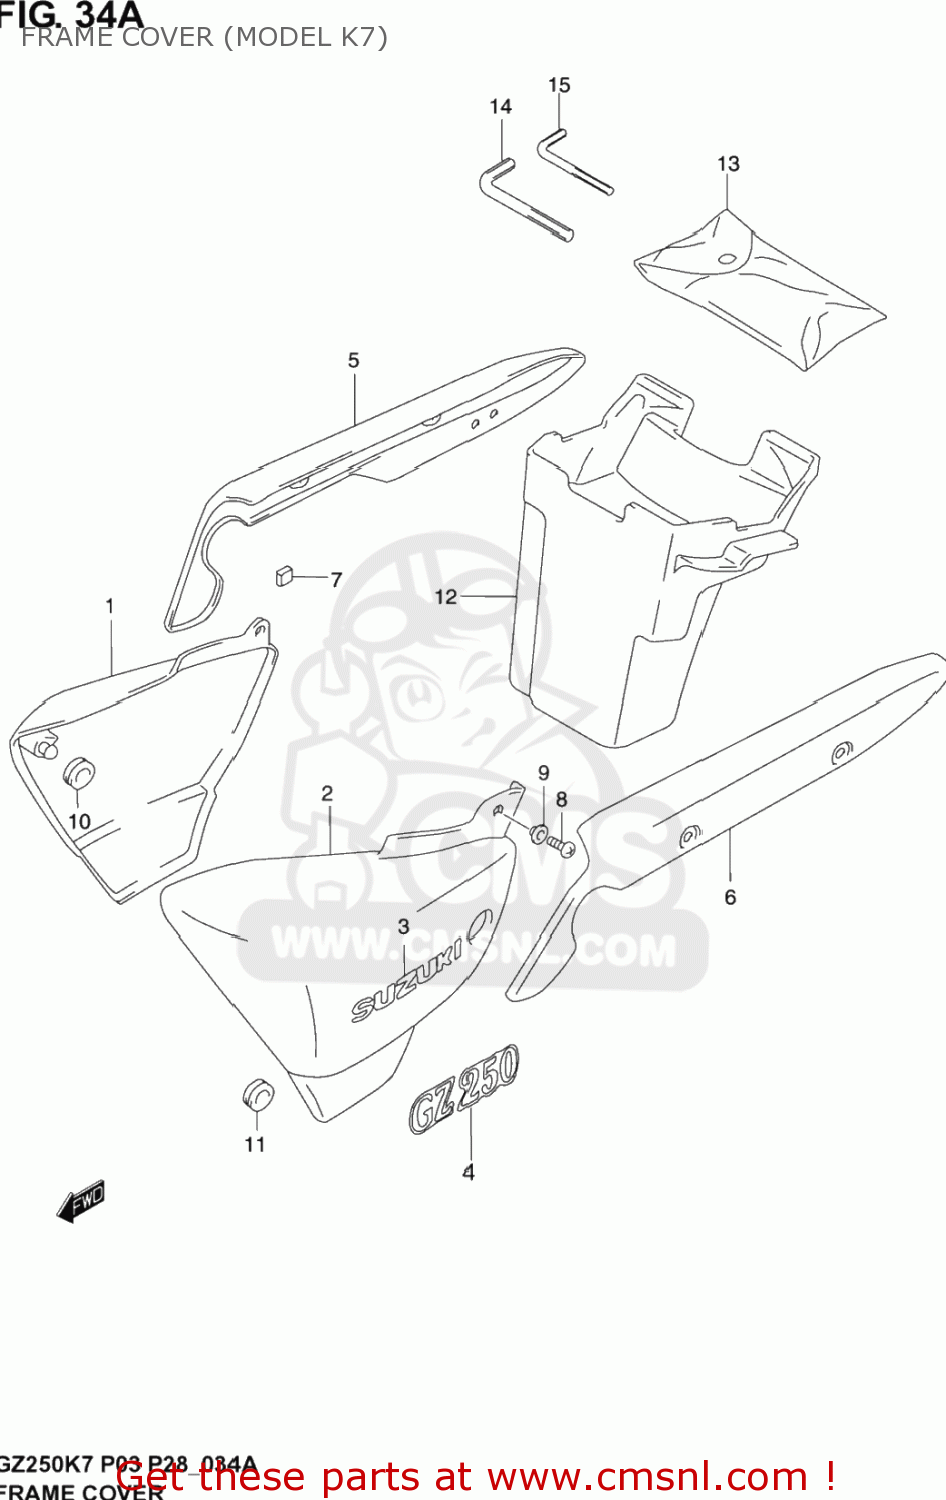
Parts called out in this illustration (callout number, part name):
1	COVER,FRAME RH
2	COVER,FRAME LH
3	EMBLEM,FRAME CO
4	EMBLEM,SUZUKI
5	COVER, FRAME REAR RH
6	COVER, FRAME REAR LH
7	CUSHION
8	SCREW 6X12
9	WASHER
10	CUSHION
11	CUSHION
12	BODY, LUGGAGE BOX
13	TOOL ASSY
14	SPANNER,HEXAGON(6)
15	SPANNER,HEXAGON(4)
